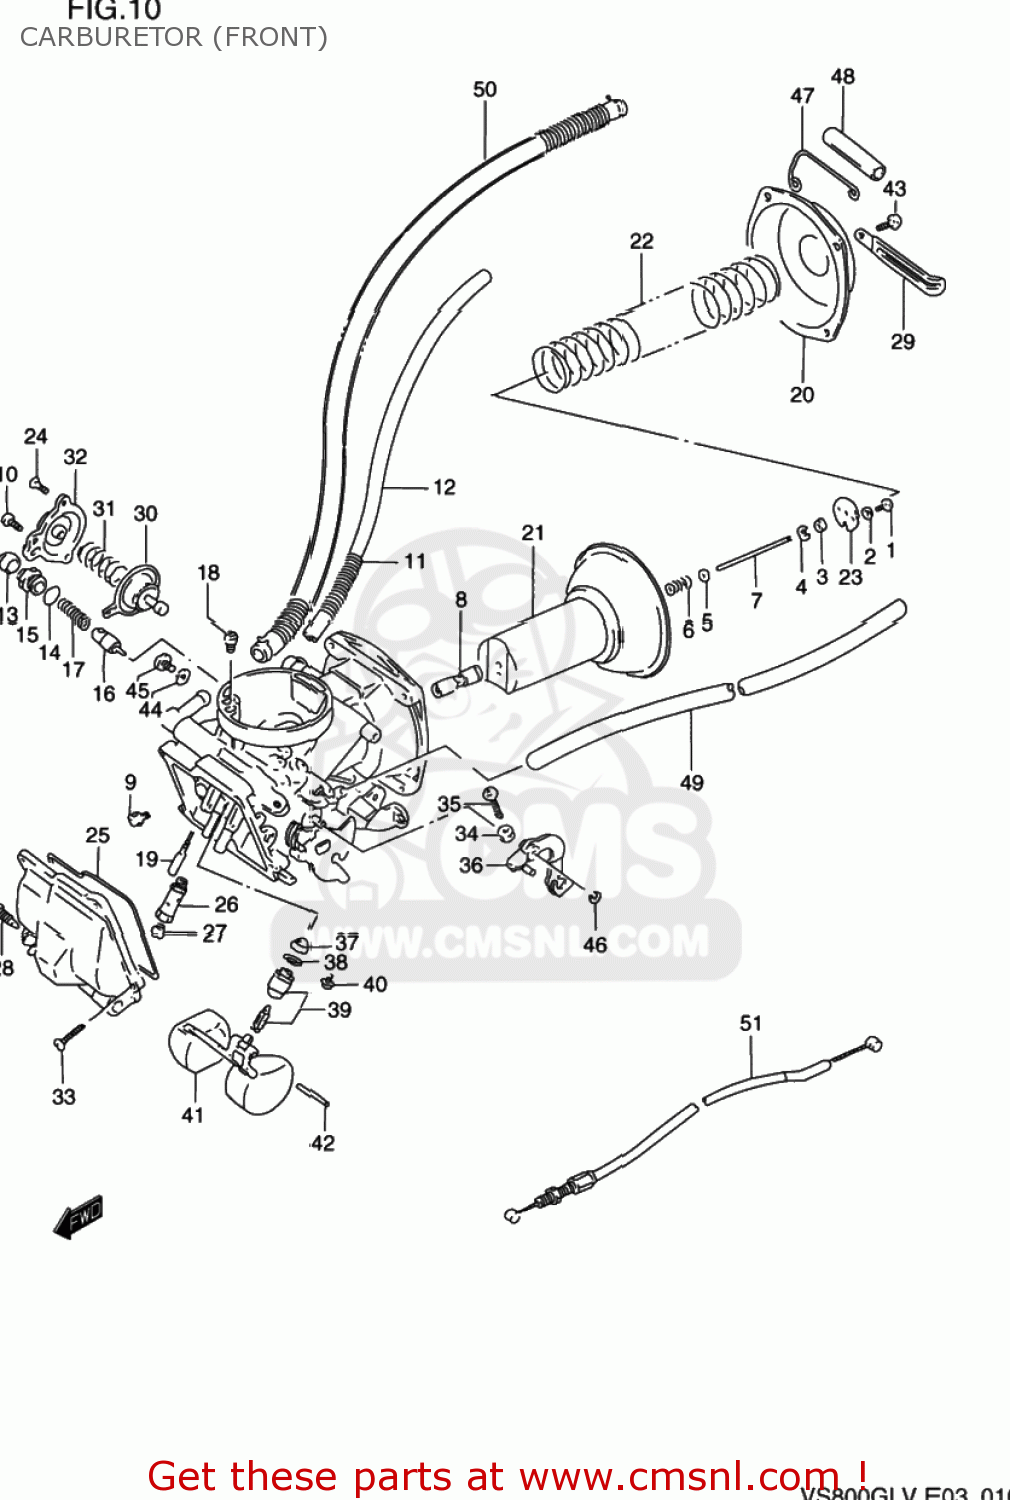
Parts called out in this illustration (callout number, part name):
1	SCREW
2	LOCK WASHER
3	RING
4	CLIP
5	WASHER
6	SPRING
7	NEEDLE,JET
8	JET,NEEDLE(P-2)
9	SCREW
10	SCREW
11	SPRING
12	HOSE
13	CAP
14	O RING
15	HOLDER,GUIDE
16	PLUNGER,STARTER
17	SPRING
18	JET,AIR(65)
19	JET,PILOT(40)
20	COVER
21	DIAPHRAGM,CARBURETOR
22	SPRING,DIAPHRAGM
23	PLATE
24	SCREW
25	O RING,FLOAT CHAMBER
26	HOLDER,MAIN JET
27	JET,MAIN(127.5)
28	PLUG
29	CLAMP L:35
30	DIAPHRAGM ASSY
31	SPRING
32	COVER
33	SCREW
34	NUT
35	SCREW
36	LEVER,ASSY
37	FILTER
38	O-RING,NEEDLE VALVE
39	VALVE ASSY,NEEDLE
40	SCREW
41	FLOAT
42	PIN,FLOAT
43	SCREW
44	GASKET,DRAIN PLUG (NAS)
45	SCREW
46	E-RING
47	CLIP
48	HOSE
49	(CA) HOSE SET,FUEL
50	HOSE
51	CABLE,IDLE SYNCRO
